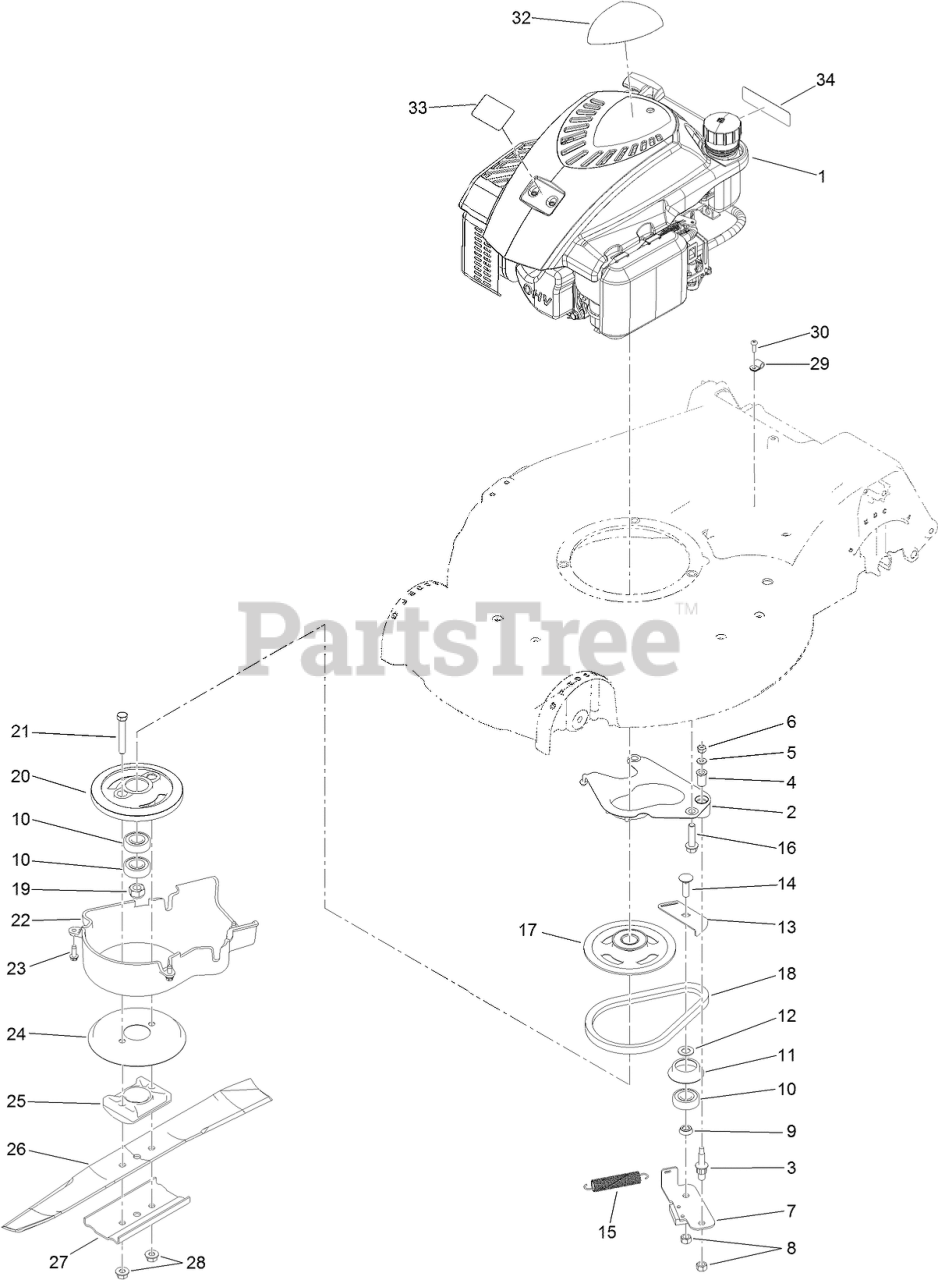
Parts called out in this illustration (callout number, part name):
1	ENGINE-1P65FC
2	PLATE-ANCHOR
3	BOLT-SHOULDER
4	BUSHING
5	WASHER-FLAT
6	NUT-LOCK, NI
7	PLATE-BRAKE
8	NUT-HEX
9	SPACER-BEARING
10	BEARING-BALL
11	RETAINER-BELT
12	WASHER-PLAIN
13	PLATE-GUIDE
14	BOLT-CARR
15	SPRING-TENSION, BRAKE
16	SCREW-HWH
17	PULLEY
18	BELT
19	NUT-HEX
20	DRUM
21	SCREW-HH
23	SCREW-HWHTF
24	DISC
25	SUPPORT-BLADE
26	BLADE-RECYCLING
27	SUPPORT-BLADE
28	NUT-FLANGE, LOCK
29	CLAMP
32	DECAL-SHROUD
34	DECAL-ARRESTER, SPARK
